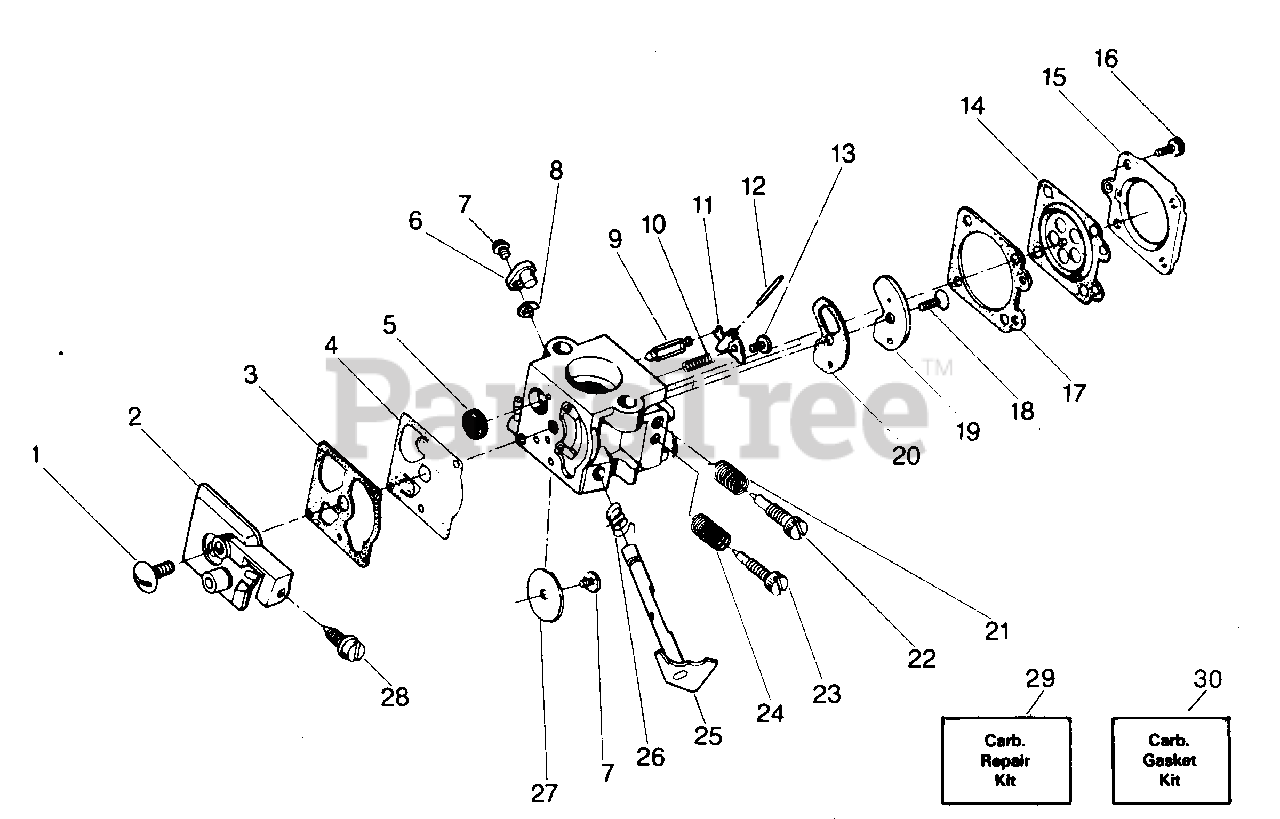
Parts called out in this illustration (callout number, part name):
1	Screw - Pump Cover
2	Pump Cover Ass'y. (Inc.28)
3	Gasket - Pump
4	Diaphragm - Pump
5	Screen - Inlet
6	Swivel Lever Ass'y.
7	Screw - Throttle Valve
8	Clip - Throttle Shaft
9	Valve - Inlet Needle
10	Spring - Metering Lever
11	Lever - Metering
12	Pin - Metering Lever
13	Screw - Metering Lever Pin
14	Diaphragm Assembly- Metering
15	Cover - Metering Diaphragm
16	Screw Assembly - Metering Cover & Throttle Shaft Clip
17	Gasket - Metering Diaphragm
18	Screw - Circuit Plate
19	Plate - Circuit
20	Gasket - Circuit Plate
21	Spring - Hi Speed Needle
22	Needle - Hi Speed
23	Needle - Idle
24	Spring - Idle Needle
25	Shaft Assembly - Throttle
26	Spring - Throttle Return
27	Valve - Throttle
28	Screw - Idle Adjustment
29	Kit Carb - Kwik Repair Kit
30	Kit Carb - Gasket/Diaphragm
